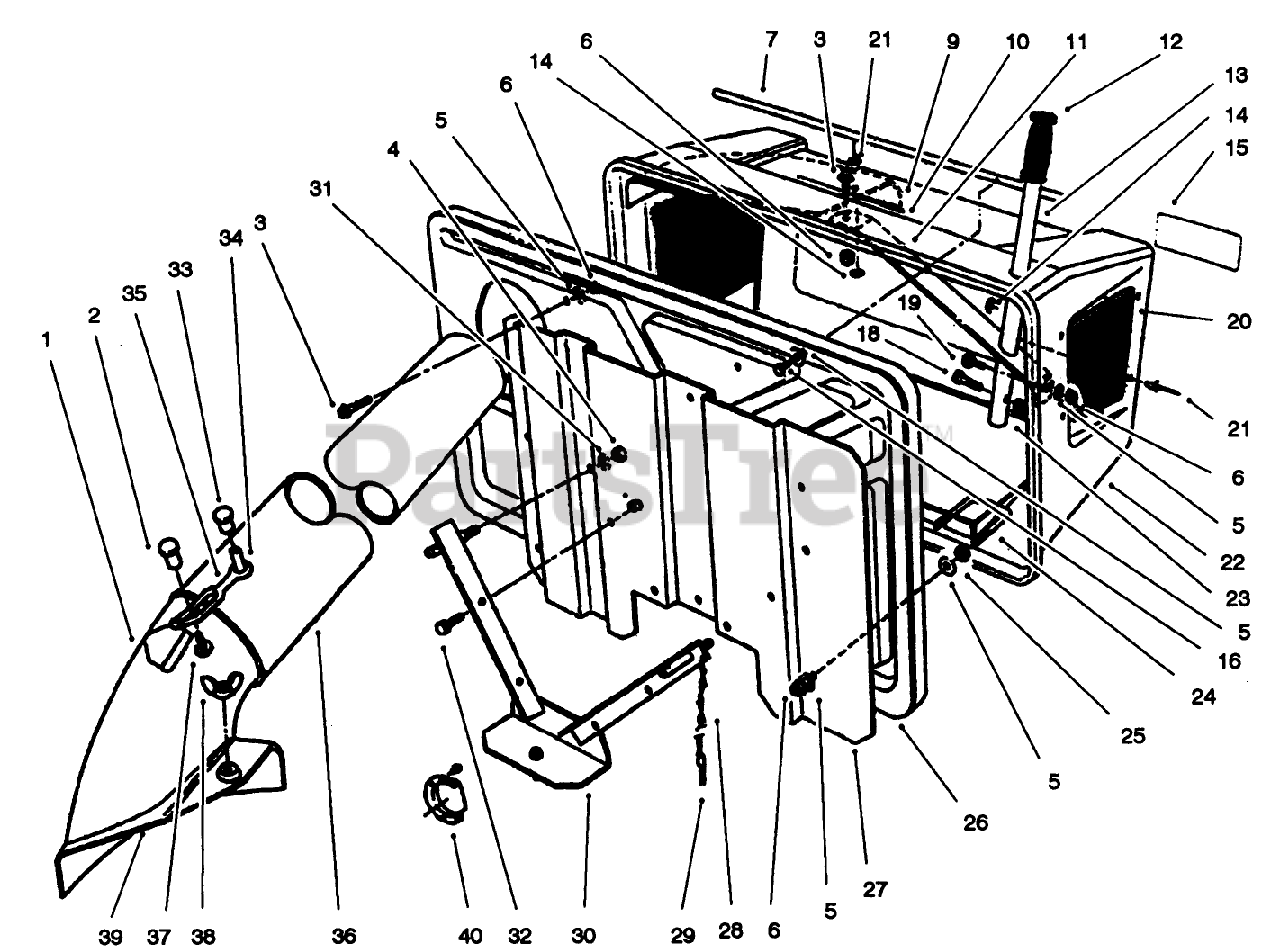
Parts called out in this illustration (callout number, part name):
3	SCREW-HHF
4	NUT-LOCK, NI
5	WASHER-FLAT
6	NUT-LOCK, NI
7	PIVOT ROD
9	DEFLECTOR
10	DECAL - WARNING
11	HANDLE GUIDE
13	HANDLE TUBE
14	WASHER-FLAT
15	DECAL-BAG, EASY EMPTY
16	SCREW-HH
18	SCREW-HH
19	BOLT-CARR
20	SCREEN
21	RIVET-POP
22	HOPPER
23	NUT-HEX, SIDE DEFORM
24	LATCH
25	NUT-HEX
29	PIN-HAIR
31	WASHER-FLAT
32	SCREW-HH
33	FASTENER-PANEL
34	SPACER-INTERLOCK
35	RETAINER-DUCT
37	SCREW-HWH
38	NUT-WING SPECL
39	CHUTE ASSEMBLY
40	MUFFLER DEFLECTOR
